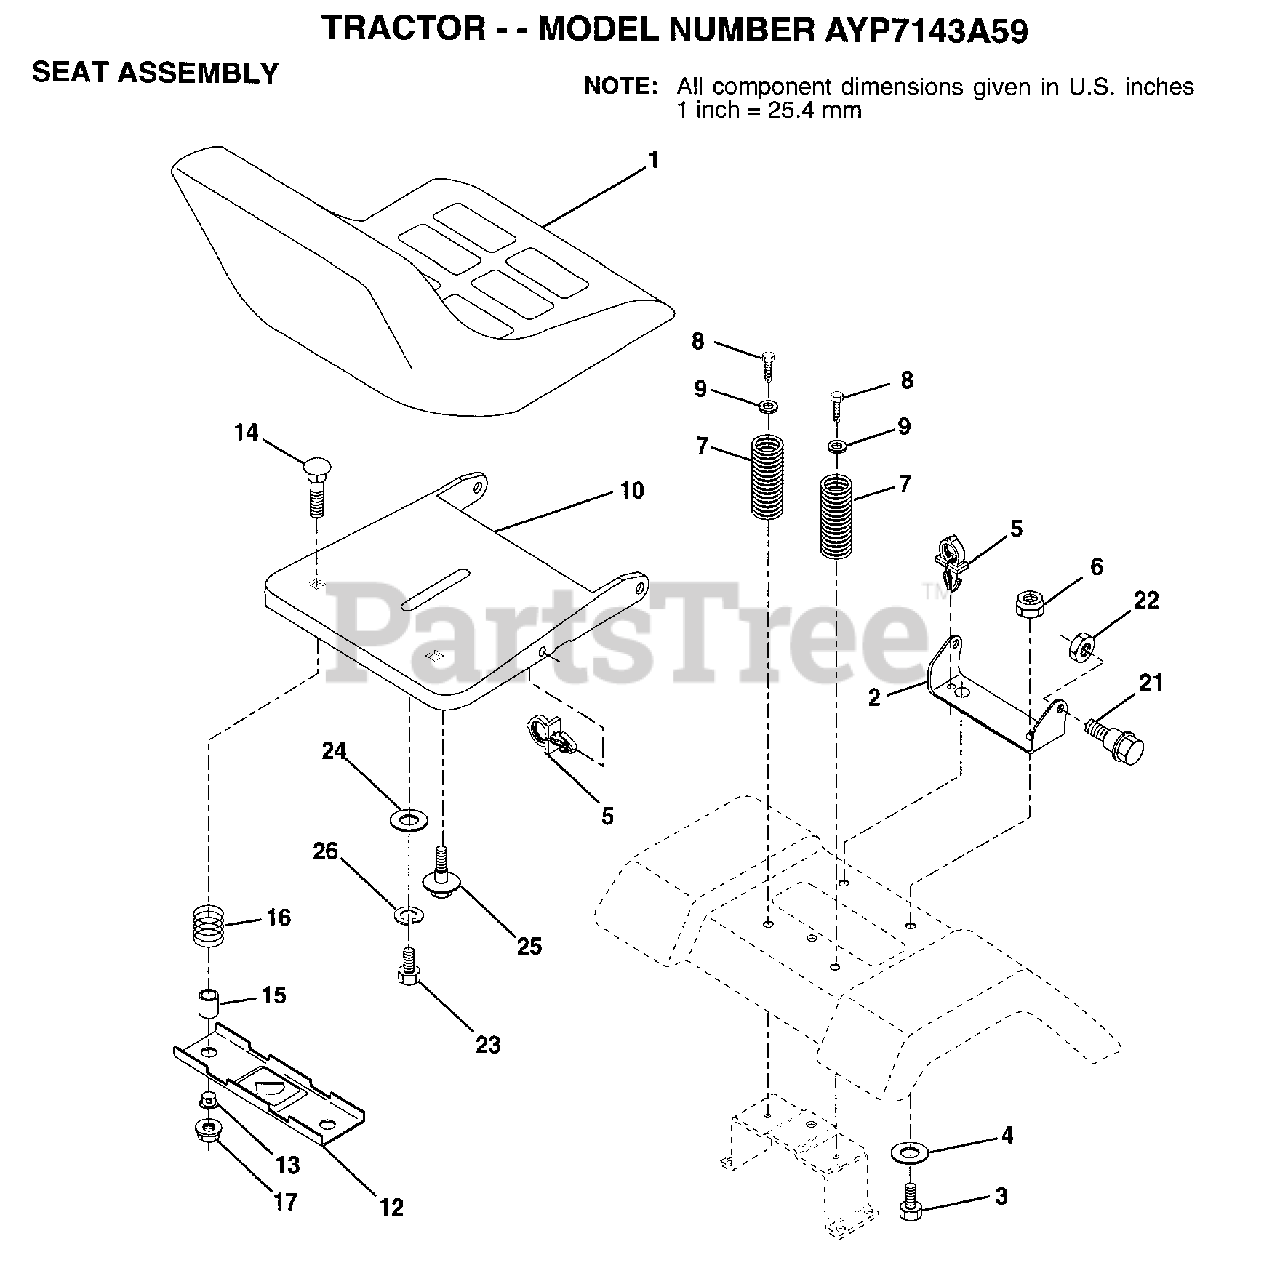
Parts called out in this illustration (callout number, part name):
2	BRACKET PVT SEAT
3	BOLT
4	WASHER PM
5	CLIP.PUSH-IN.HING
6	NUT
7	SPRING COMPRESSIO
8	SCREW GTV
9	WASHER
12	BRKT SWITCH
13	BUSHING
15	SPLIT SPACER
16	SPRING
21	BOLT.SHLD.5/16-18
22	NUT
23	BOLT
24	WASHER
25	"BOLT,SHOULDER"
26	LOCKWASHER
